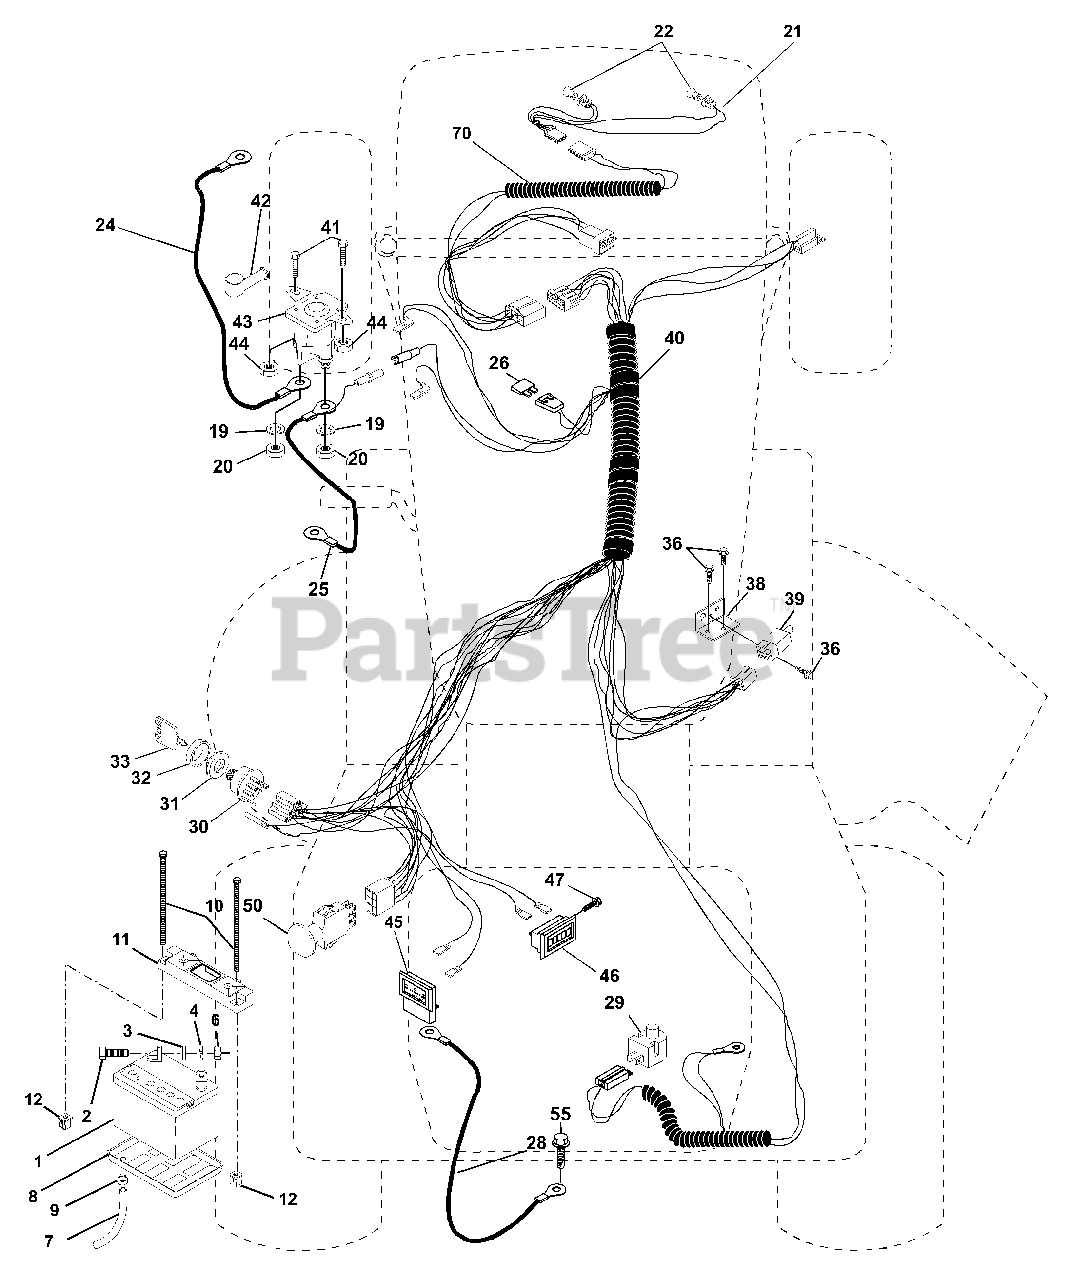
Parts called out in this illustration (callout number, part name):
1	Battery 12 Volt 35 AMP Wet
2	Bolt Hex Hd 1/4-20unc X 3/4
3	Washer 9/32 X 5/8 X 16 Ga.
4	Washer Lock Hvy Helical 1/4
6	Nut Fin Hex 1/4-20 Unc
7	Tube Plastic 46" Front
8	Tray, Battery 7.80 x 5.25 Blk
9	Clamp Hose Olive
10	Bolt BTR FRT 1/4-20 x 7.5 zinc
11	Holddown Battery, Dash mount
12	Nut, Push Nylon 1/4 battery FRT
19	Washer Lock 1/4
20	Nut Jam Hex 1/4-20 Unc
21	Harness Asm Light W/4152j
22	Bulb Light #1156
24	Cable Battery 6 Ga 22" red
25	Cable Battery 6 Ga 22" w/16W
26	Fuse 30 AMP Auto Green
28	Cable Ground 6 Ga 21" black
29	Switch Plunger Nc Gray
30	Switch Ign 4 pos w/lights
31	Nut Ignition
32	Cover Sw Ignition
33	Key Ign Modleded Generic
36	Screw Tap Hex #10-24unc X 1/2
38	Bracket, Switch, Interlock
39	Switch Intlk Clutch Grey 4 Term
40	Harness Ign. Elec. HM P/L
41	Bolt Blk Fin Hex 1/4 - 20 x 1/2
42	Cover Terminal Red
43	Solenoid
44	Nut Keps Hex 1/4-20 Unc
45	Ammeter, retangular 15 amp
46	Meter, Hour
47	Screw 10-24 x 1/2 Black
50	Switch PTO 3 PTD Black
55	Screw THDROL 5/16-18 x 1/2 TYT
70	Harness, Eng.
